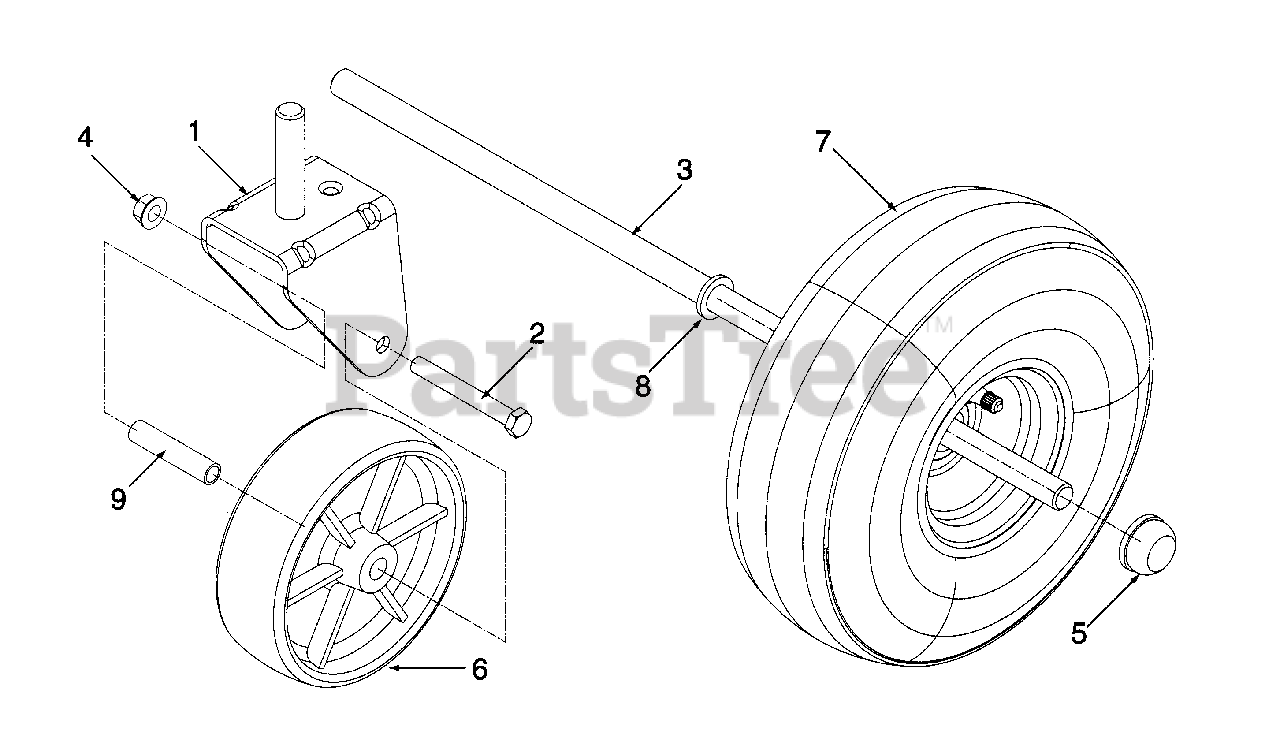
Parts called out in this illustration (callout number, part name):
2	HEX CAP SCREW 3/8-16 3.00
3	RR AXLE SHAFT
4	FLANGED LOCK NUT 3/8-16
5	PUSH CAP 5/8
6	WHEEL 6.00 x 2.00
7	WHEEL COMPLETE 10 x 4 x 4
8	FLAT WASHER 5/8 id x 1.00 od
9	SPACER .384 id x .500 od x 2.3
